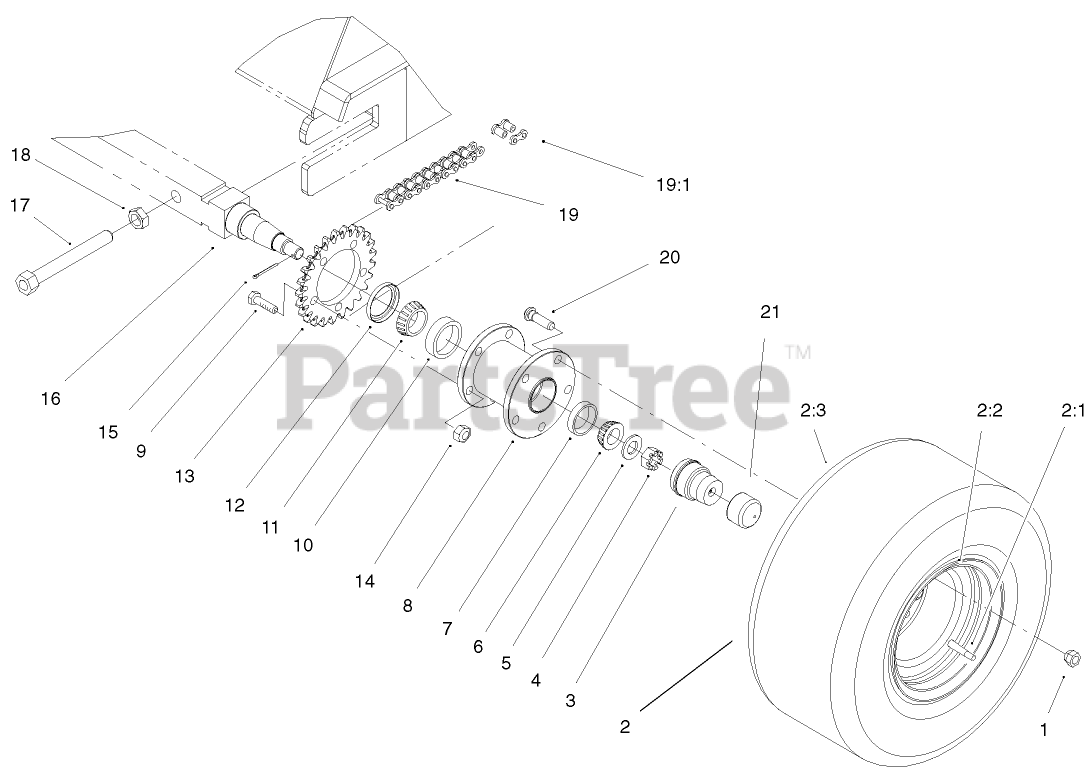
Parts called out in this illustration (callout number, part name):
1	NUT-LUG
2	ASM - WHEEL/TIRE
2:1	TUBE-TIRE
2:2	WHEEL
2:3	TURF TIRE-18 X 8.50-8
3	PROTECTOR - BEARING
4	NUT-HEX, SLOTTED
5	WASHER-FLAT
6	BEARING-CONE, TAPERED
7	BEARING-CUP, TAPERED
8	Hub-Front
9	SCREW-HH
10	CUP-BEARING, TAPERED
11	CONE-BEARING, TAPERED
12	SEAL-BEARING, WHEEL
13	SPROCKET-25T
14	NUT-LOCK, NI
15	PIN-COTTER
17	BOLT-TENSION
18	NUT-JAM
19	CHAIN-ROLLER
19:1	LINK-CONNECTING
20	STUD-TYPE, DRIVE
21	BOOT - PROTECTOR
